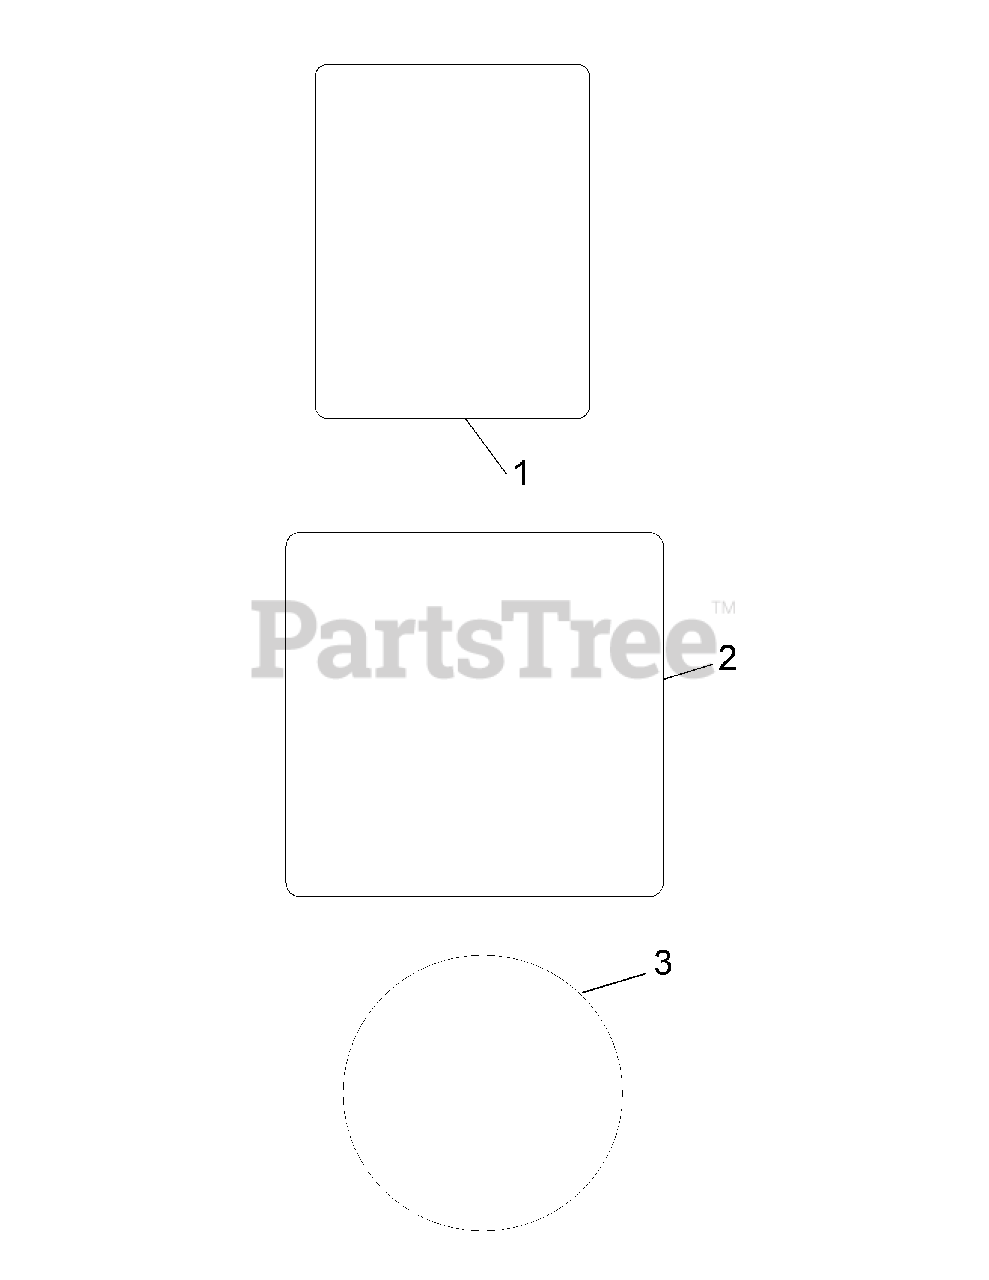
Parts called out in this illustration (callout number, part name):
1	Clear Laminate Decal
2	HDAC 694cc/CV-CH682 Decal
3	Grass Screen Decal
